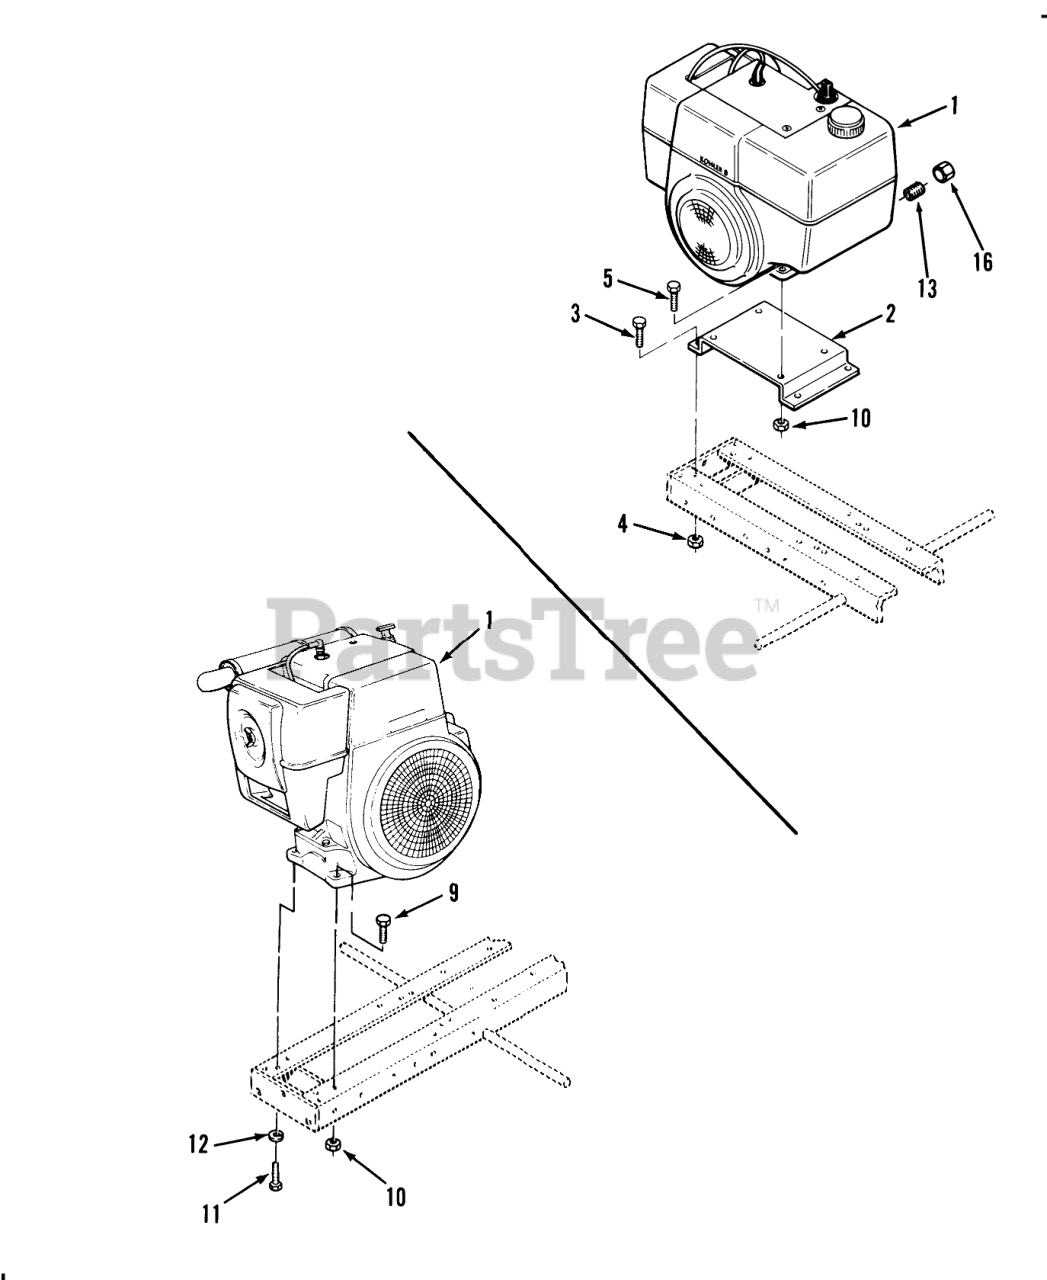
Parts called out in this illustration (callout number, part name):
1	Engine-8HP-Kohler M-8-S Spec PS-301511
2	Engine Base
3	BOLT
4	NUT
5	Bolt
9	BOLT
10	NUT
11	BOLT
12	LOCKWASHER
13	Nipple 1/2"
16	CAP-PIPE 1/2 IN
